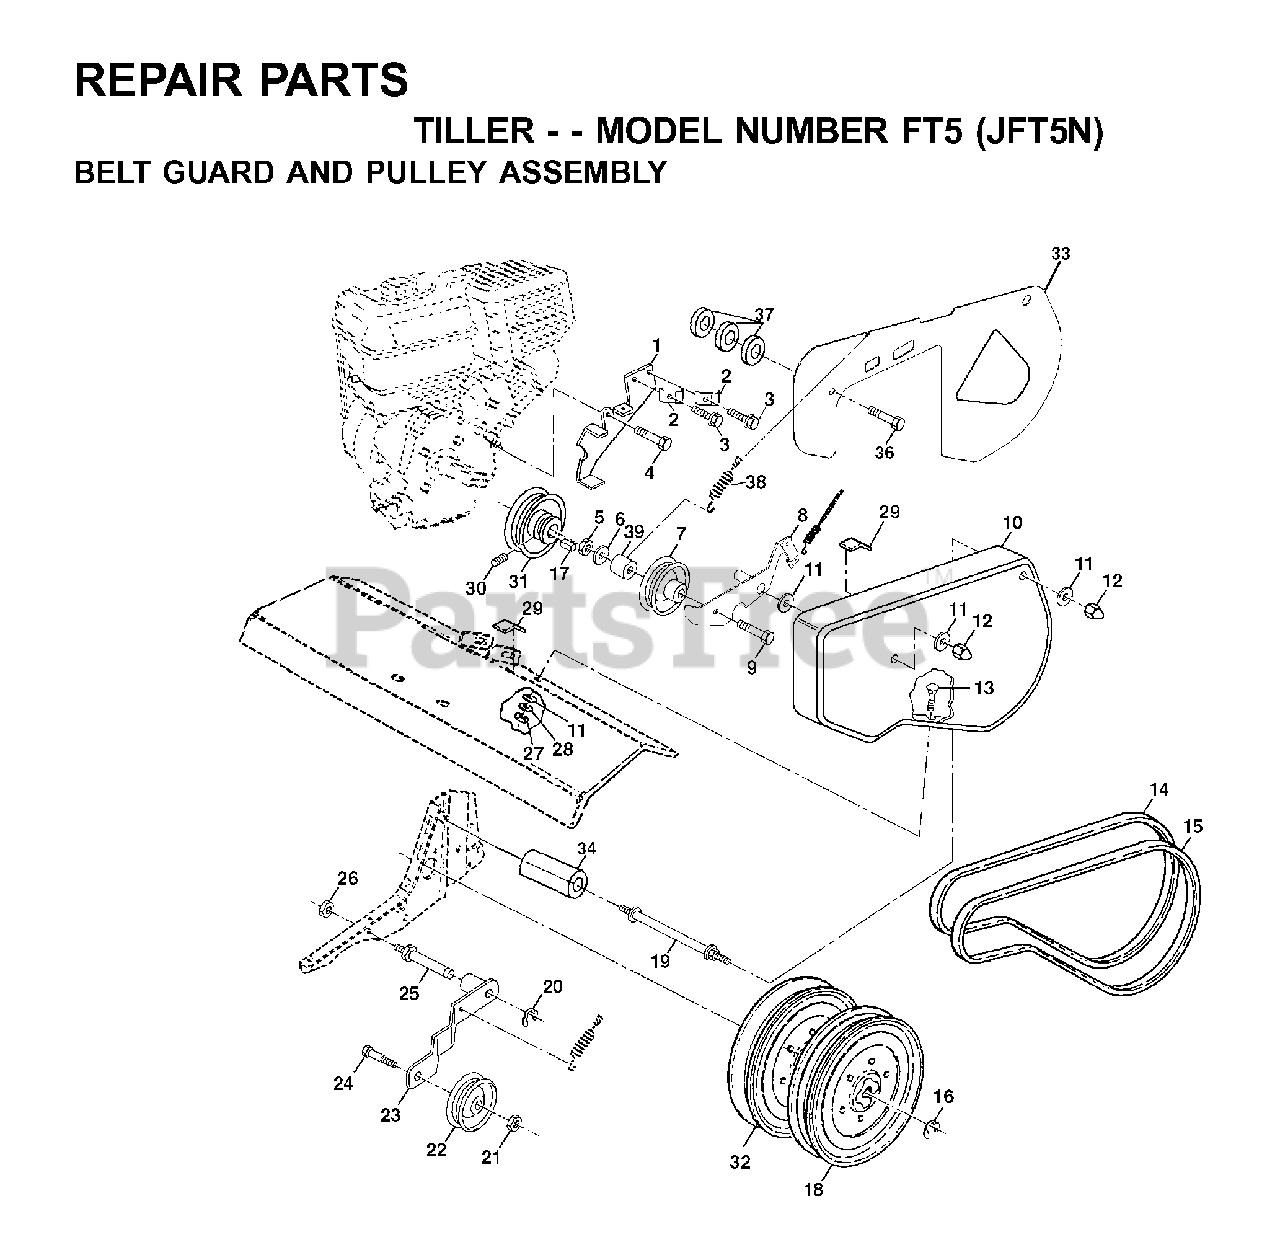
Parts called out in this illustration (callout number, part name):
2	CONDUIT CLIP T
3	TAPPING SCREW
7	PULLEY
8	ARM
9	BOLT
11	WASHER
12	CAP
15	BELT
16	RETAINING RING LT
18	SHEAVE,TRANS."D"
20	KLIP RING TI
21	NUT
22	PULLEY, IDLER
23	ARM, IDLER
25	SHAFT.IDLER.TILLER
26	JAM NUT TI
27	NUT
28	LOCKWASHER
29	PAD IDLER TI
32	SHEAVE.TRANS
37	WASHER
38	SPRING.EXTENSION
